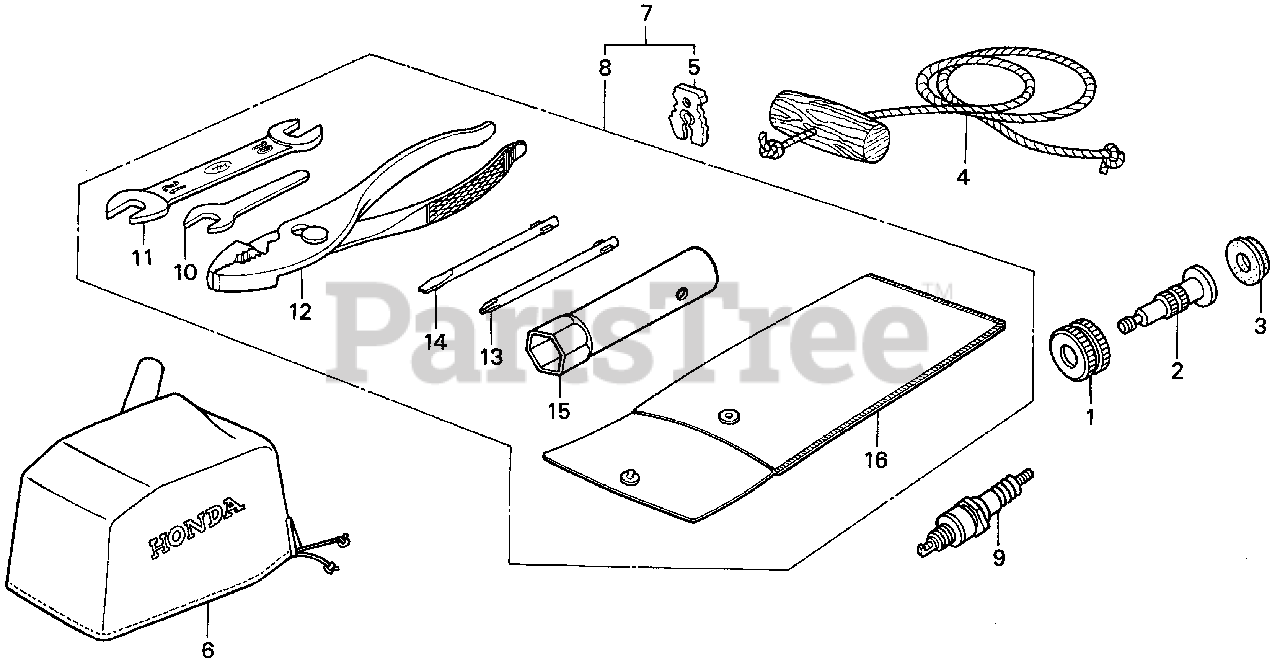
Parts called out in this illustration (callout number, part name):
1	NUT, WATER MOUTH
2	JOINT, WATER HOSE
3	SEAT, WATER MOUTH
4	ROPE, STARTER (#5X55")
6	ENGINE COVER
8	TOOL KIT (NOT AVAILABLE)
9	SPARK PLUG (BPR5ES) (NGK)
9	SPARK PLUG (W16EPR-U) (DENSO)
10	WRENCH (8MM) (OPEN END)
11	WRENCH (10X12) (OPEN END)
12	PLIERS (135MM)
13	SCREWDRIVER 1, PHILLIPS (NO.2)
14	SCREWDRIVER 3, STRAIGHT SLOT (NO.2)
15	WRENCH, BOX (P21)
